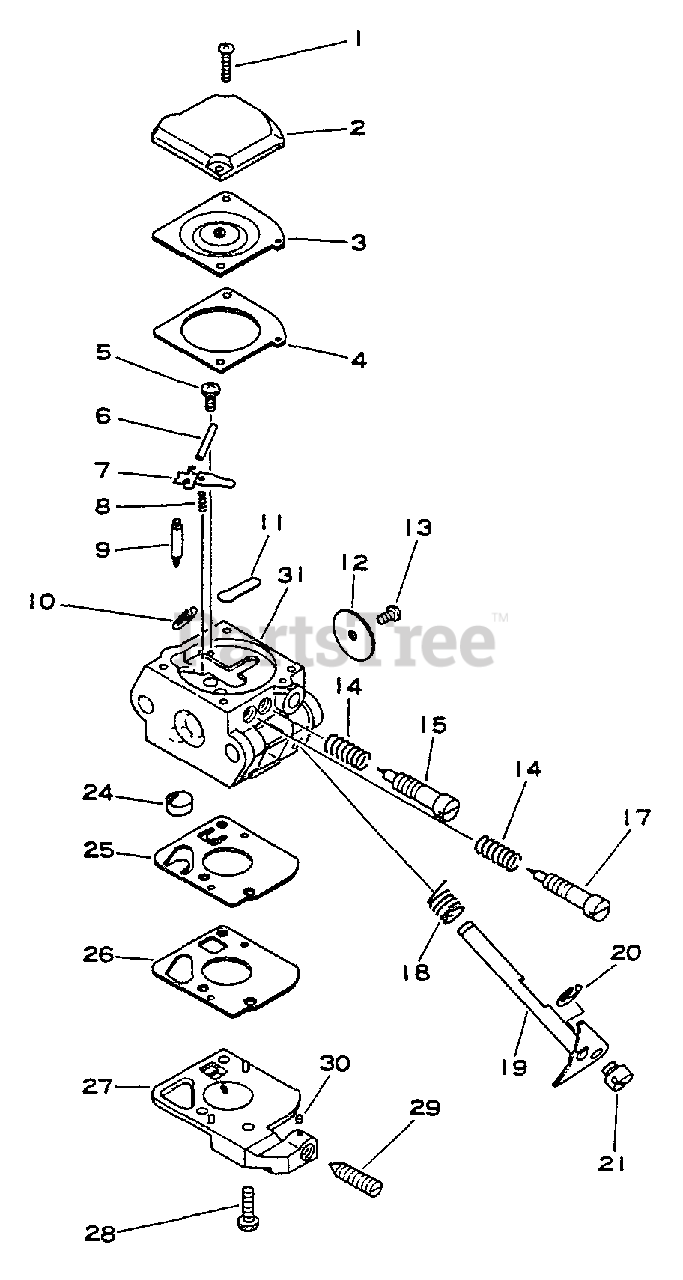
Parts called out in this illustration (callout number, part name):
2	COVER, METERING
3	DIAPHRAGM
4	GASKET, DIAPHRAGM
5	SCREW, METERING LEVER PIN
6	PIN
7	LEVER, METERING
8	SPRING, METERING LEVER
9	VALVE, INLET NEEDLE
10	RING, RETAINING
11	PLUG, WELCH
12	VALVE, THROTTLE
15	NEEDLE - HIGH SPEED
17	NEEDLE - LOW SPEED
18	SPRING, RETURN
19	SHAFT, THROTTLE
20	RING, RETAINING
24	STRAINER
25	DIAPHRAGM, PUMP
26	GASKET, PUMP
27	BASE, PURGE
28	SCREW, PUMP COVER
29	SCREW, IDLE ADJUST
30	PIECE, FRICTION
